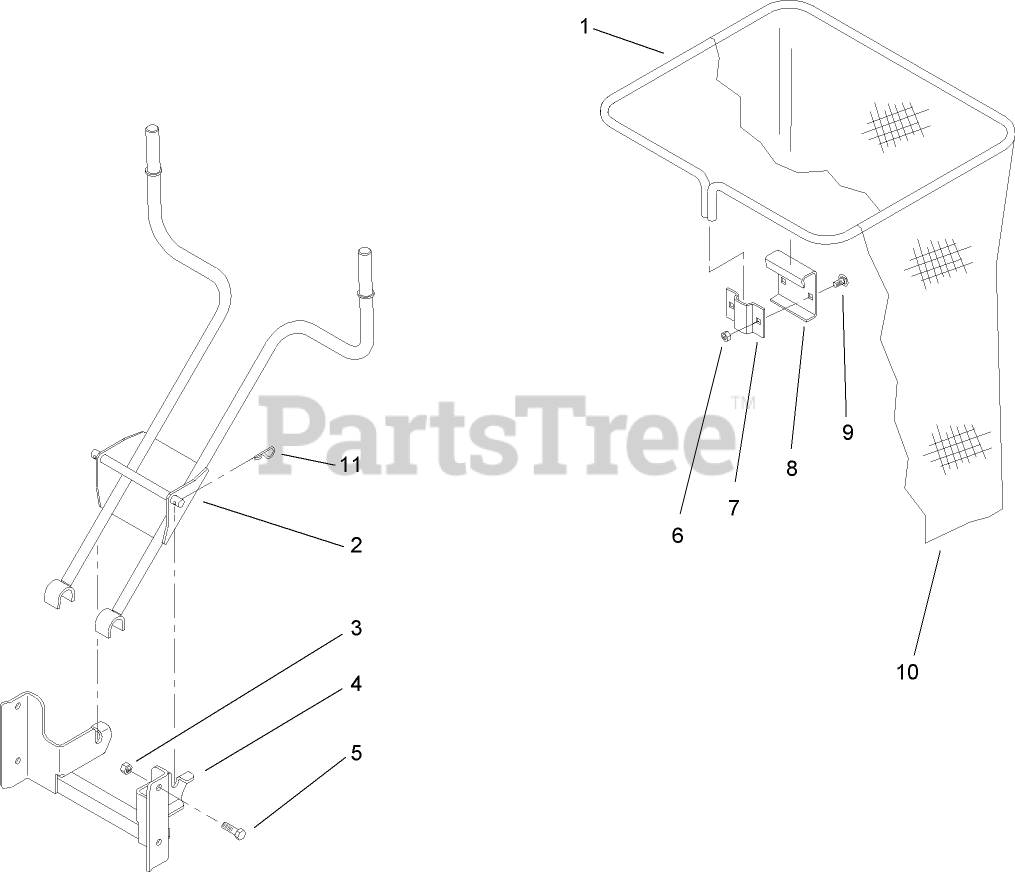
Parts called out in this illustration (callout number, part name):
1	FRAME-BAG
2	BRACKET-ATTACH, QUICK
3	NUT-LOCK, NI
4	SUPPORT-BAGGER
5	SCREW-HH
6	NUT-LOCK, NI
8	HANGER-BAG
9	BOLT-CARR
10	BAG-DEPTH
11	PIN-COTTER, HAIR
